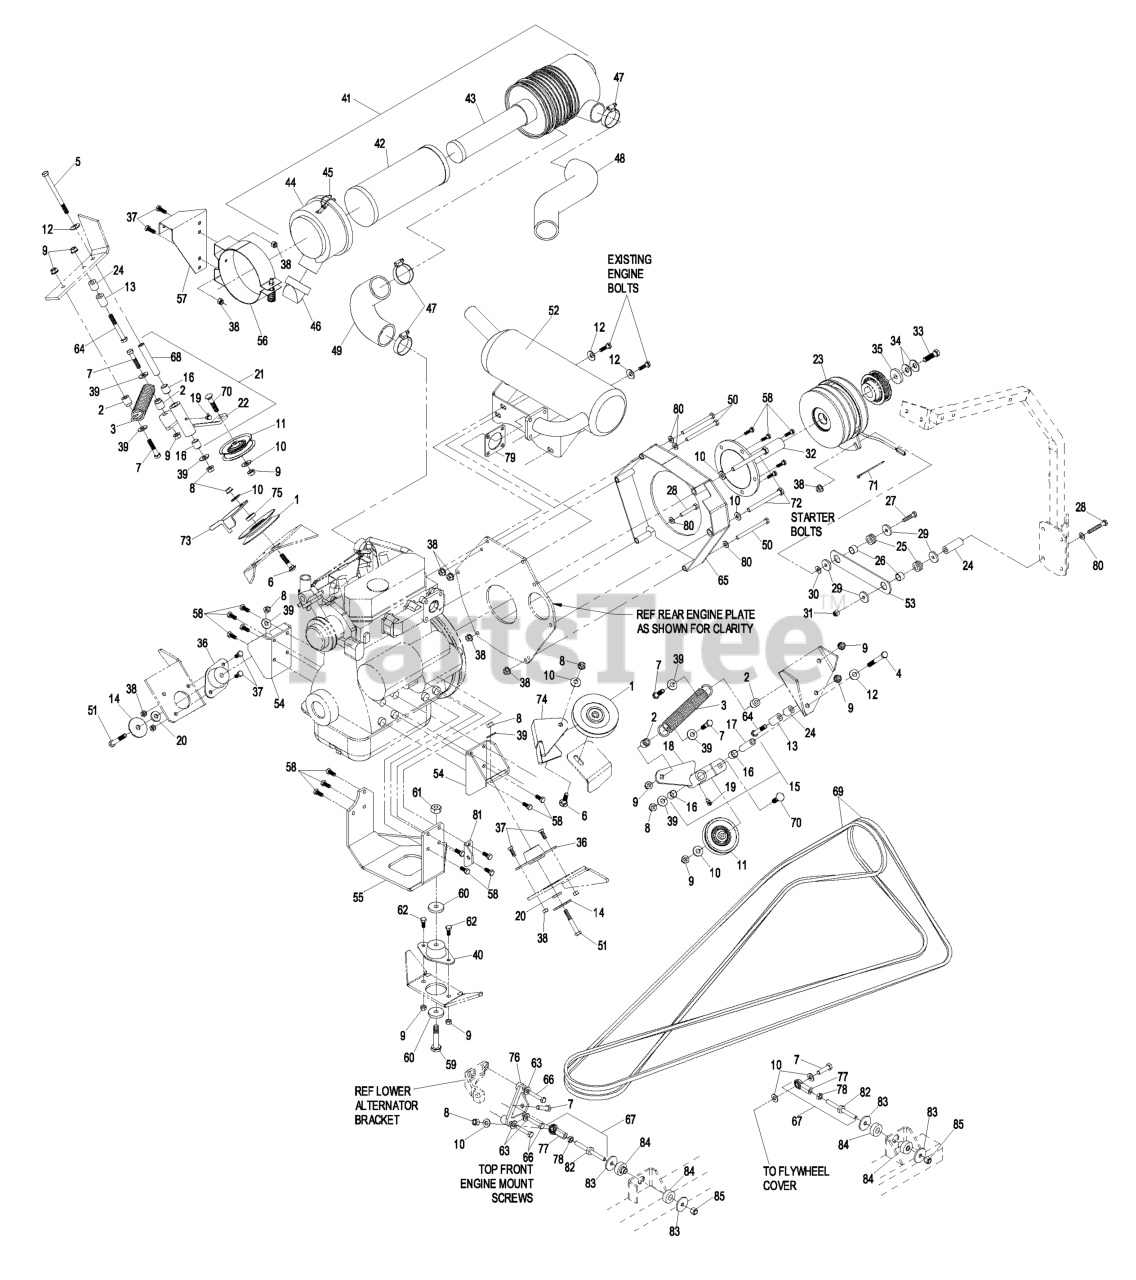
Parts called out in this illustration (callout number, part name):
2	SPACER-TIGHTENER, BELT
3	SPRING-EXTENSION
4	SCREW-HH
5	SCREW-HH
6	BOLT-CARR, SHORT NECK
7	SCREW-HH
8	NUT-LOCK, NI
9	NUT-HHF, WHIZ
10	WASHER-FLAT
12	WASHER-BELLEVILLE
13	SPACER-HYDRO CONTROL, LH
14	WASHER-FLAT
16	SLEEVE-BEARING
17	BUSHING-TIGHTENER, PIVOT
19	FITTING-GREASE, 90 DEG
24	SPACER-STRAP, CLUTCH
25	GROMMET
27	SCREW-HH
28	SCREW-HH
30	WASHER-FLAT
31	NUT-LOCK, NI
32	SHAFT-STUB
33	SCREW-HH
34	WASHER-SPRING
35	WASHER-CLUTCH
36	ISOLATOR-SIDE
37	SCREW-HH
39	WASHER-FLAT
40	ISOLATOR-REAR
42	FILTER-AIR
43	FILTER-AIR, SAFETY
44	COVER-FILTER, AIR
45	LATCH-CLEANER, AIR
46	VALVE-VACUATOR
47	CLAMP-HOSE
48	HOSE,PLENUM TO AIR CLNR
50	SCREW-HH
51	BOLT-CARR
52	MUFFLER KIT
53	STRAP-CLUTCH / BRAKE
54	LH AND RH ENGINE MOUNT AS
55	REAR ENGINE MOUNT ASM
56	BRACKET-FILTER, AIR
57	MOUNT-CLEANER, AIR
58	SCREW-HH
59	SCREW-HH
60	WASHER-THRUST
61	NUT-LOCK, NI
62	SCREW-HH
63	WASHER-SPRING
64	SCREW-HH
65	COVER-FLYWHEEL
66	SCREW-HH
67	BALL JOINT LINK ASM
68	BUSHING-TIGHTENER, PIVOT
69	BELT-V
70	SCREW-CARR
71	TIE-PLASTIC
72	SCREW-HH
73	GUARD-BELT SHEAVE, RH
74	GUARD-BELT SHEAVE, LH
75	SPACER-BRACKET, GUIDE
76	BRACKET-ENGINE, FRONT
77	JOINT-BALL, END
78	NUT-HJ
79	GASKET-MUFFLER
80	WASHER-PLAIN
81	BRACKET-GROUND
82	LINK,REAR A-T AXIAL
84	ISOLATOR-LINK
85	NUT-LOCK
